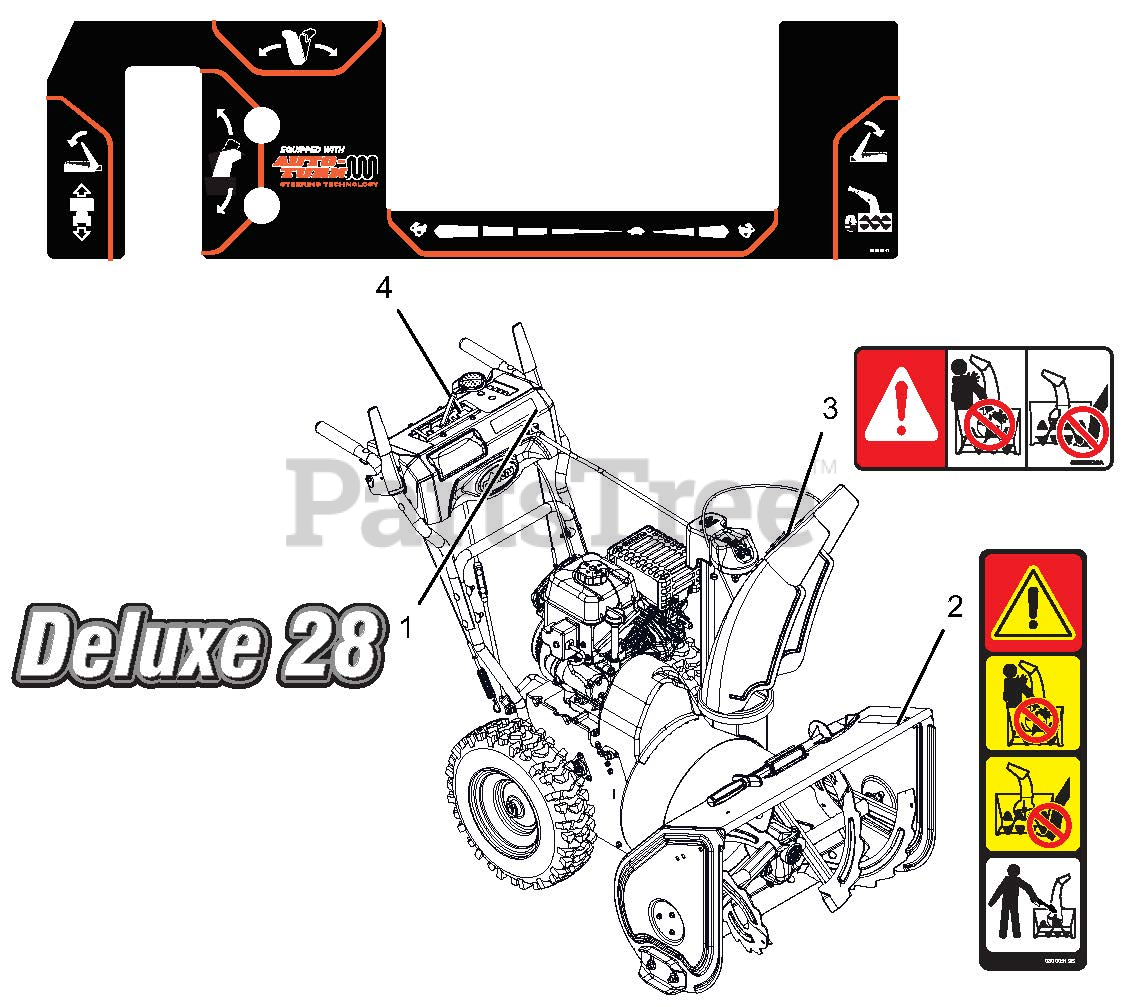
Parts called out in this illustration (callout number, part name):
1	DECAL,SM DASH-DELUXE 28 SHO
2	DECAL, DANGER - ROTATING PARTS
3	DECAL, DANGER
4	DECAL,CONTROL-SML,AT,ID
